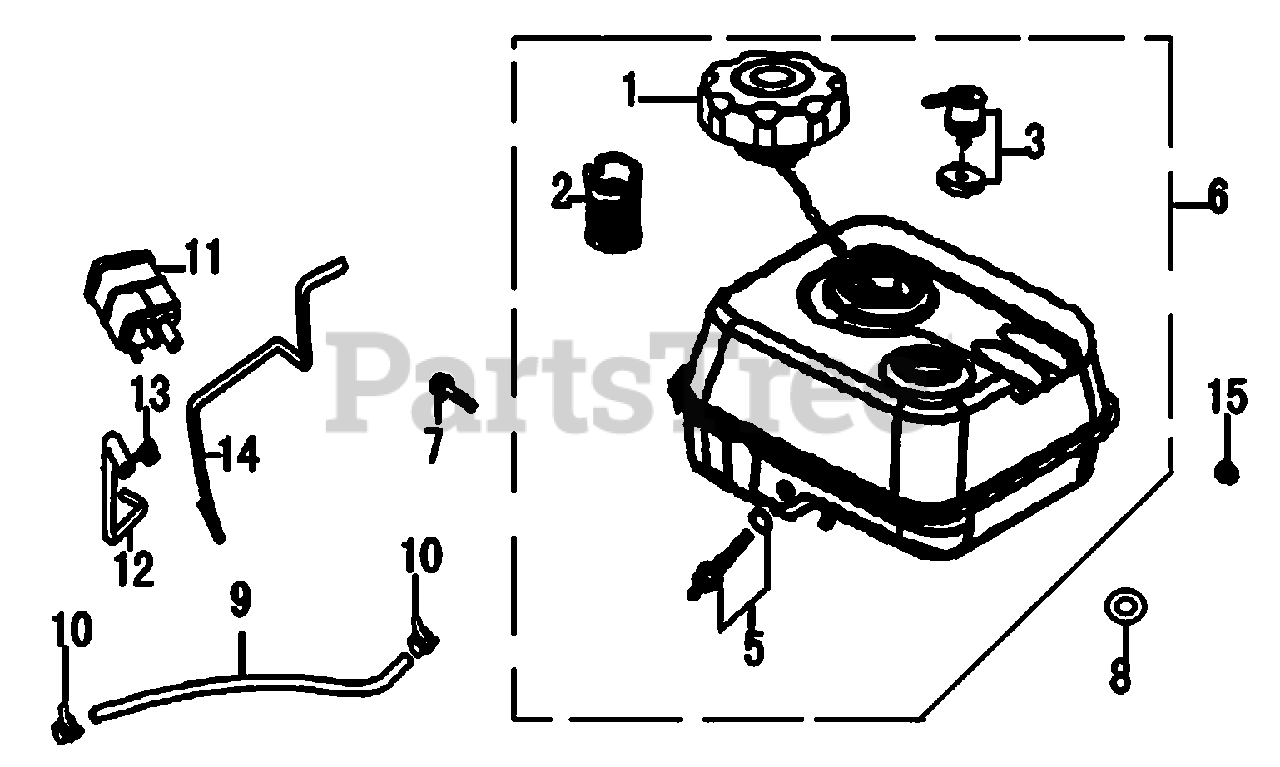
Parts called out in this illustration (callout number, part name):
1	CAP, FUEL
2	FILTER, FUEL
3	ROLL OVER VALVE
5	JOINT ASSY.,FUEL TANK
6	ASSY, FUEL TANK W/ROV
7	BOLT, FLANGE 6×25
8	WASHER, RUBBER
9	HOSE, FUEL
10	CLAMP/COLLAR
11	CARBON CANISTER ASSY
12	HOSE,AIRCLNR TO CARBONCANISTER
14	HOSE, FORMED (ROV)
15	NUT, FLANGE 6MM
